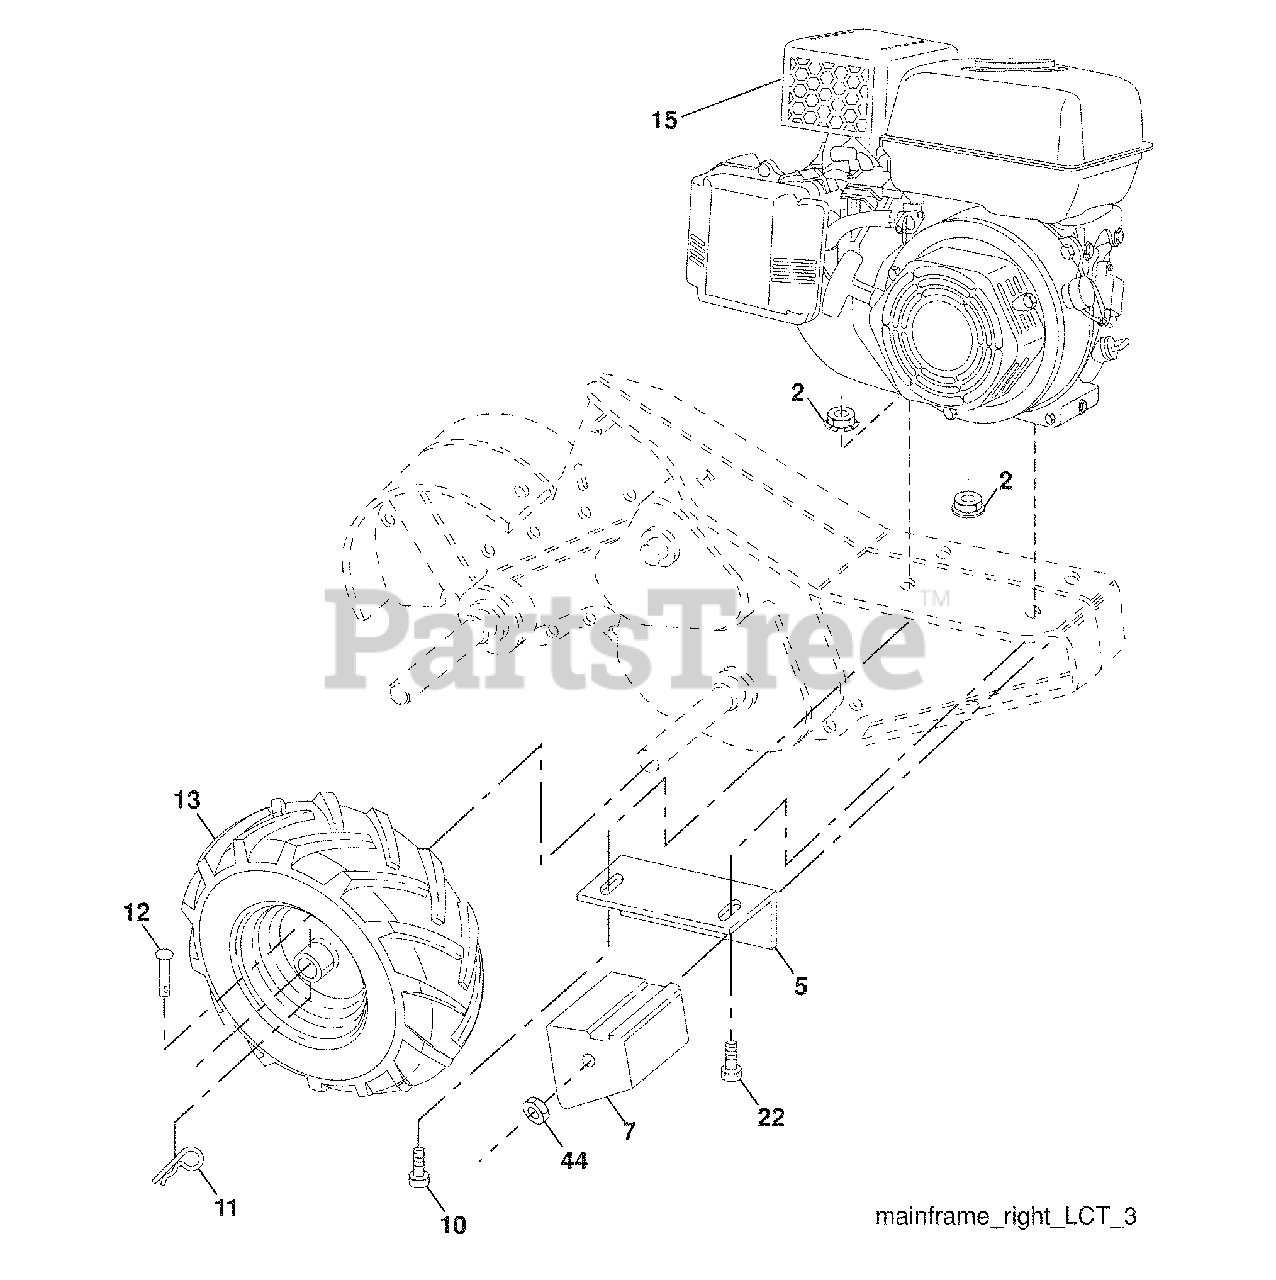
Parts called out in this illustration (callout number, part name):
2	Locknut, Hex, Flange 5/16-18
5	Bracket, Reinforcement RH
7	Counter Weight,
11	Clip, Hairpin
12	Rivet, Drilled
22	Bolt, Hex 5/16-18 x 1-1/2
44	Nut, Keps Hex 3/8-16 unc
